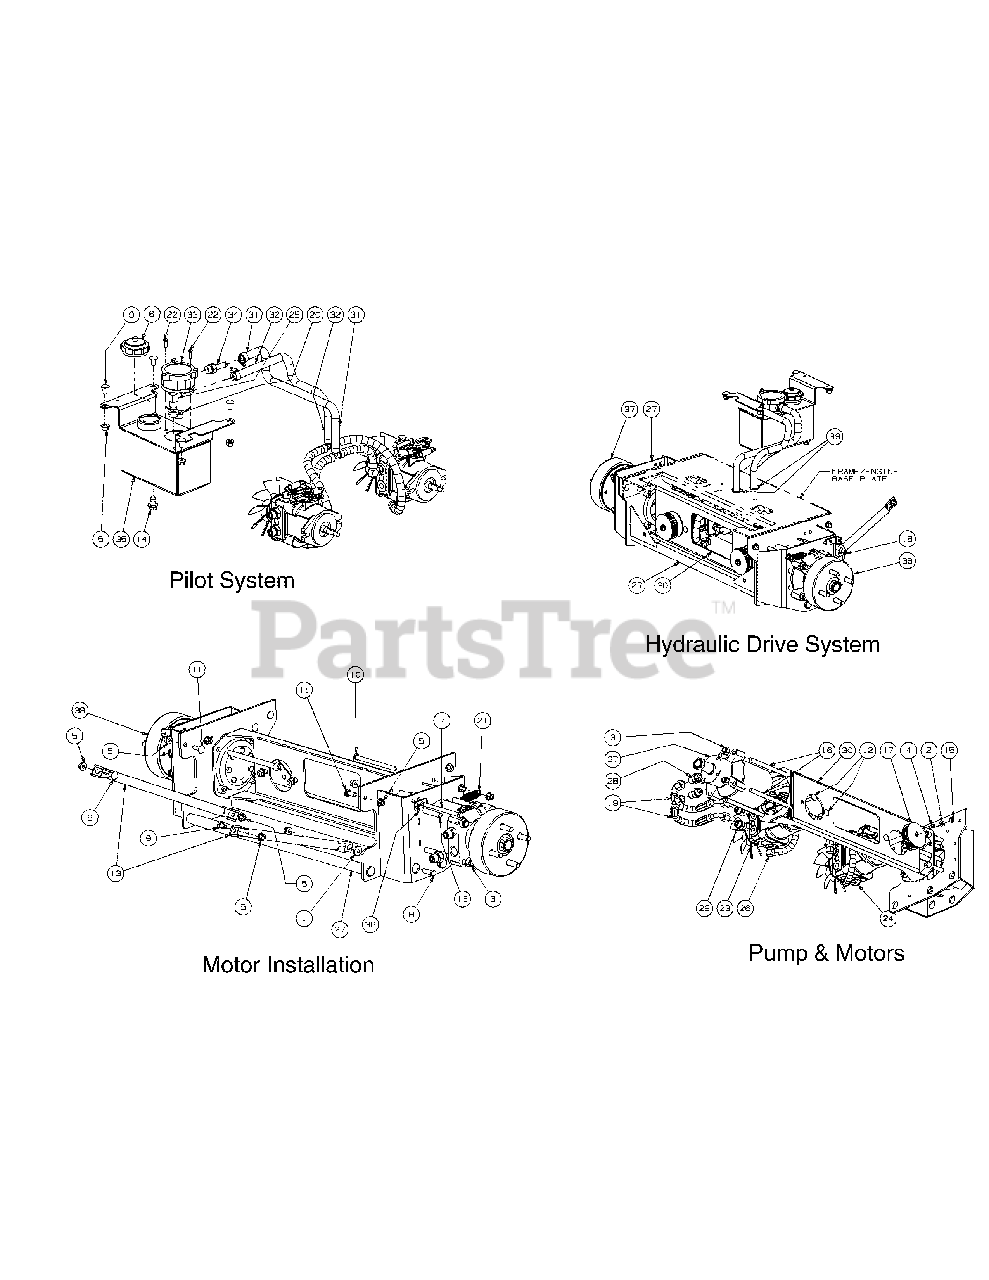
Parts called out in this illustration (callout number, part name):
1	Idler Washer
2	Flat Washer, 3/8
3	Washer lock 3/8 zinc
4	Key, 3/16" x 7/8"
5	Flange Lock Hex Nut, 3/8-16
6	Cap, Hydro Oil Tank
7	Hex Cap Screw, 3/8-16 x 5.00
8	Hex Cap Screw, 3/8 -16 x 1.25
9	Carriage Bolt, 3/8-16 x .75 LG.
10	Carriage Bolt, 3/8-16 x 5.50
11	Carriage Bolt, 3/8-16 x 1
12	Carriage Screw, 3/8-16 x 1.25
13	Strut Frame
14	Oil Pan Drain Plug w/ Seal
15	Hex Nut, 3/8-24
16	Socket Head Capscrew, 1/2-13; 6-1/2
17	Hydro Pulley Pump
18	Hose Assembly, RH
19	Hose Assembly, LH
20	Grommet Fitting, .54 ID x .78 OD
21	Spring Extension, .740 OD x 2.656
22	Socket Low Head Cap Screw, 1/4-20 x 0.75
23	Hydro Pump, BDP-12, LH
24	Hydro Pump, BDP-12, RH
25	Fitting Elbow Spur, 5/8 x 1/2
26	Fitting Elbow, 9/16 x 1/2
27	Hydro Motor Frame Assembly
28	Adaptor Fitting, 8 x 10
29	Adaptor Fitting, 8 x 8
30	Hydro Pump Mounting Bracket
31	Hose Assembly, Pilot includes:
31	Hose, .50 ID x .75 OD
32	Hose Assembly, Drain includes:
32	Hose, .50 ID x .75 OD
33	Hydraulic In-Tank Filter includes:
34	Fitting, 3/4 ORB x 1/2 Tube
35	Hydraulic Tank Assembly
36	Rear Cable Mounting Bracket
37	Hydro Motor, Left Hand Assembly w/ Brake & Drum
38	Hydro Motor, Right Hand Assembly w/ Brake & Drum
39	Gromment, .75 ID
